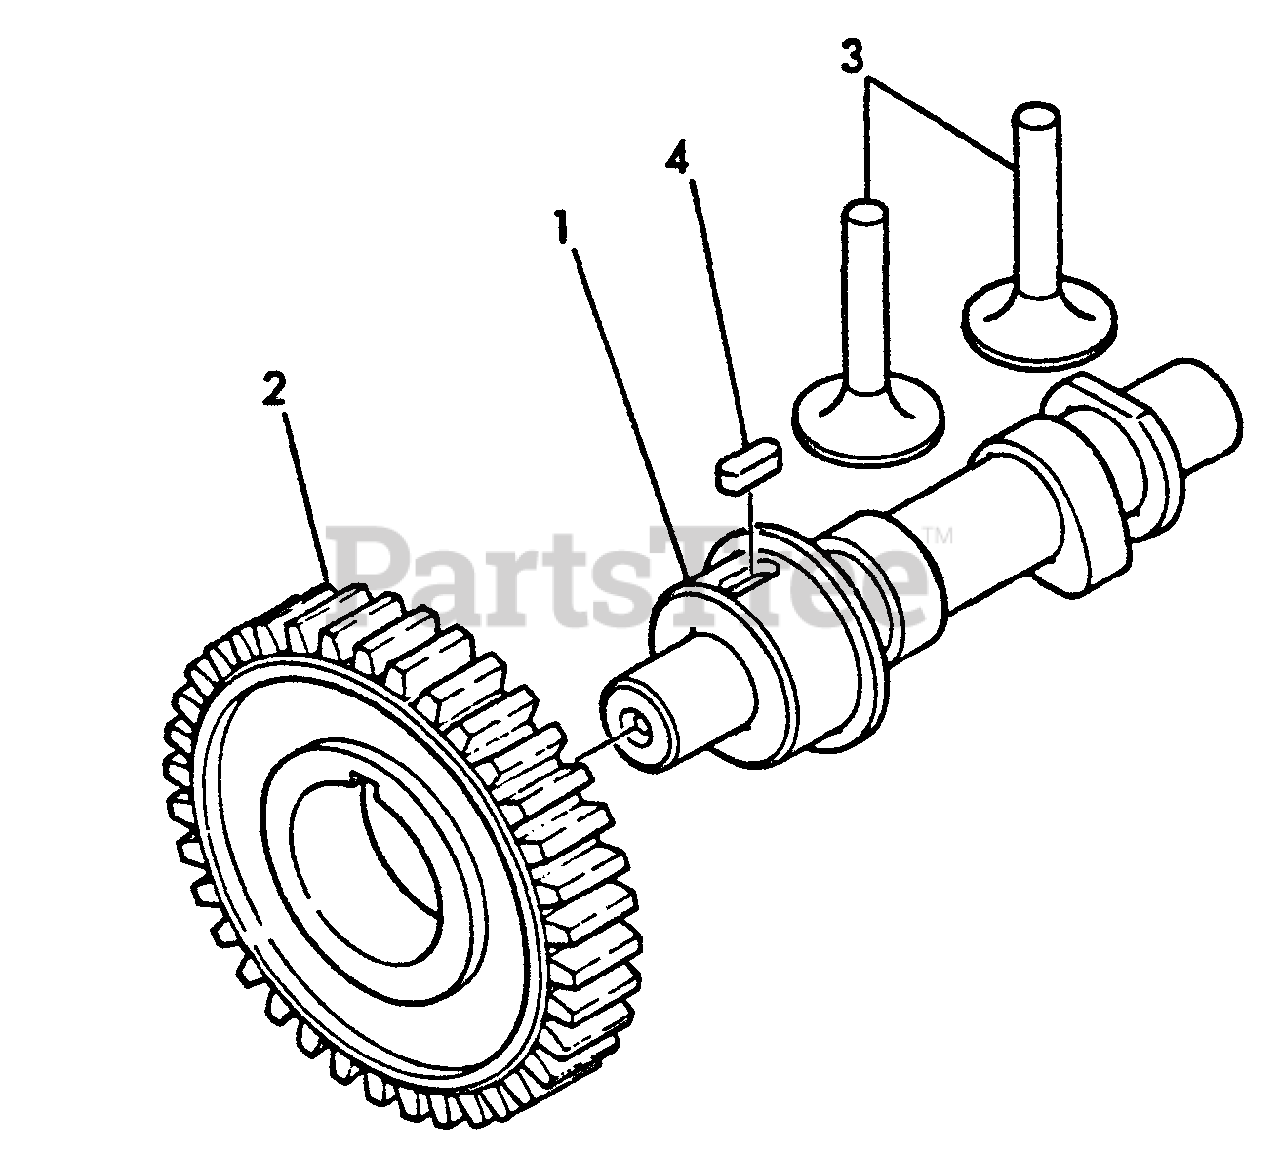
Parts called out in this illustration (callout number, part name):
1	CAMSHAFT
2	GEAR, CAMSHAFT
3	TAPPET
4	KEY - 4×10
